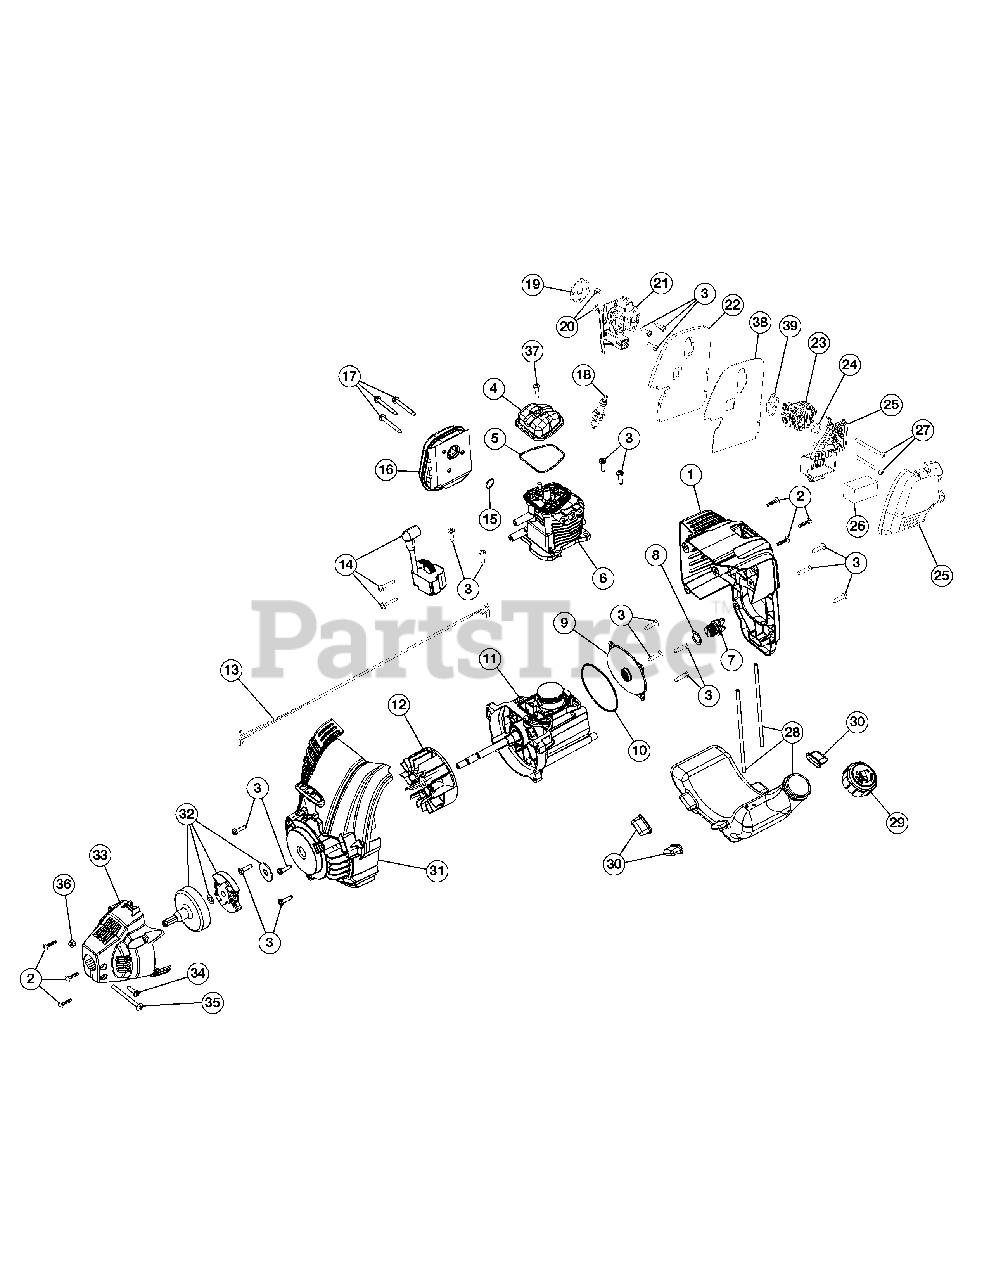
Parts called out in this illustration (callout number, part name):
1	Engine Cover Assembly (Incl. 2 & 3)
2	Cover Screw
4	Rocker Cover
5	Rocker Cover O-Ring
6	Cylinder Assembly
7	Oil Plug (Incl. 8)
8	Oil Plug O-Ring
9	Crankcase Cover
10	Crankcase Cover O-Ring
11	Crankcase Assembly (Incl. 10)
12	Flywheel Assembly
13	Lead Wires
14	Module Assembly
15	Muffler Gasket
16	Muffler Assembly (Incl. 15 & 17)
17	Muffler Screw
18	Spark Plug
19	Insulator Gasket
22	Heat Shield
23	Carburetor
25	Air Cleaner Cover Assembly (Incl. 26)
26	Air Filter
28	Fuel Tank Assembly w/Fuel Lines (Incl. 29)
30	Fuel Tank Pads
31	Starter Housing Assembly (Incl. 3)
32	Clutch Assembly
33	Clutch Cover (Incl. 2)
34	Anti-Rotation Screw
35	Clamp Screw
37	Rocker Cover Screw
